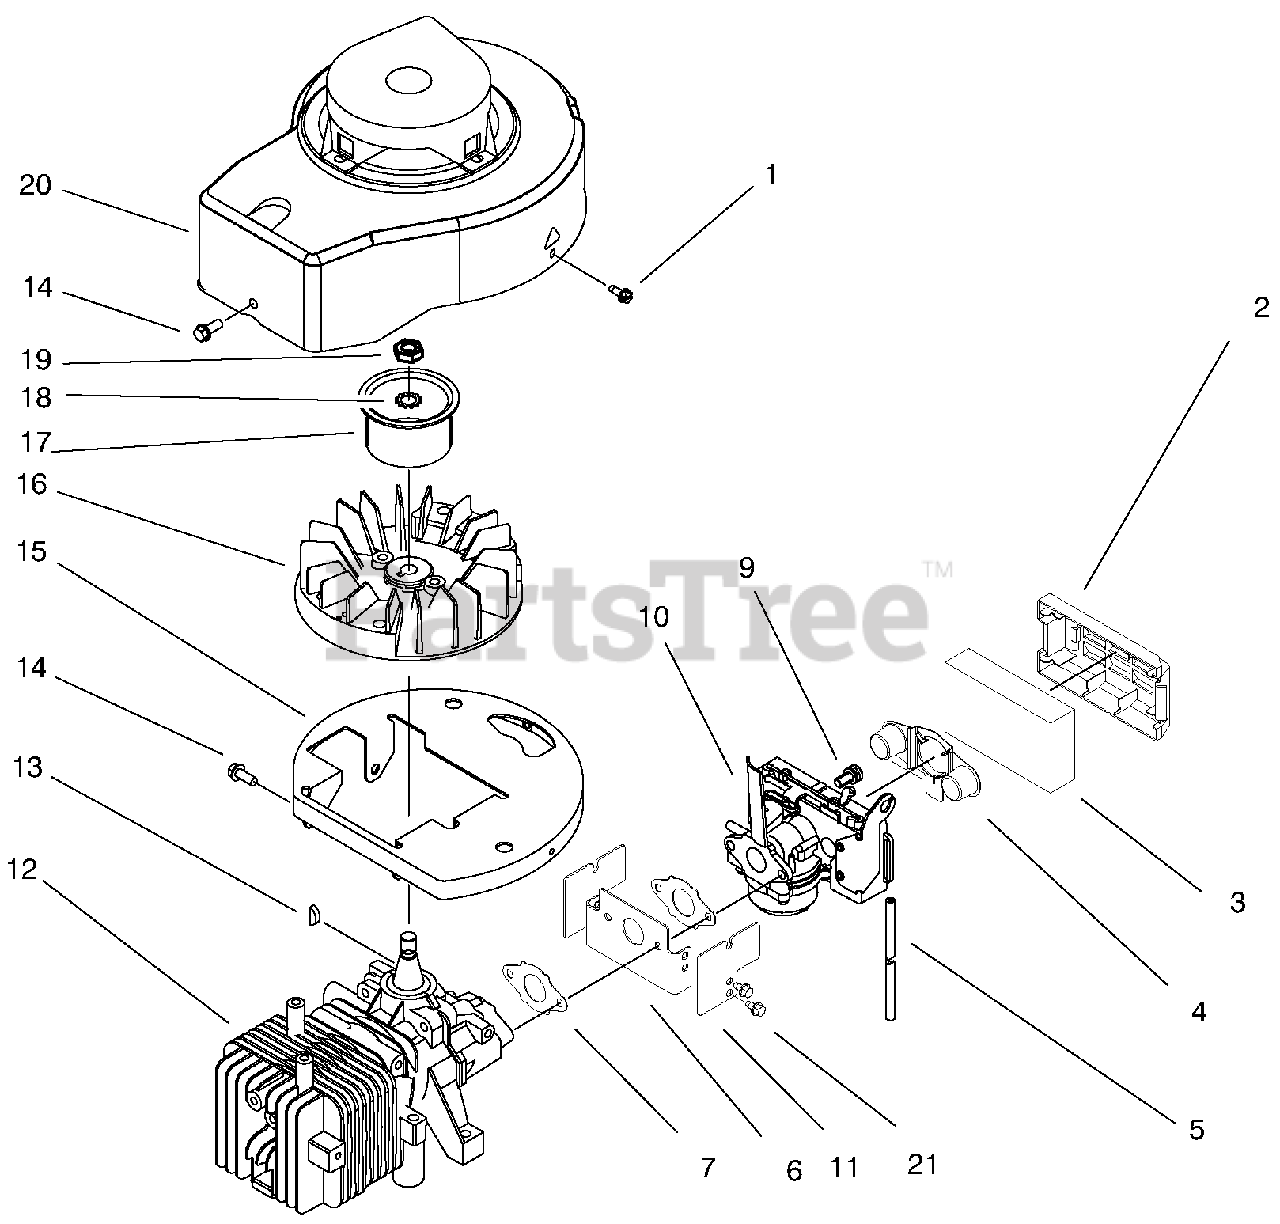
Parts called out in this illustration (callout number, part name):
1	SCREW VF
2	Cover-Air Filter
3	ELEMENT-AIR FIL VF
4	SHIELD-FUEL V
5	HOSE-PRIMER
6	SHIELD-CARB V INTL
7	GASKET-CARB VF
10	Carburetor Assembly
11	SHIELD- GOV. V INTL
12	Short Block Assembly
14	SCREW
15	Base-Shroud
16	FLYWHEEL(MACH) V
17	HUB-STARTER V
18	WASHER-LOCK
20	SHROUD
21	SCREW V
